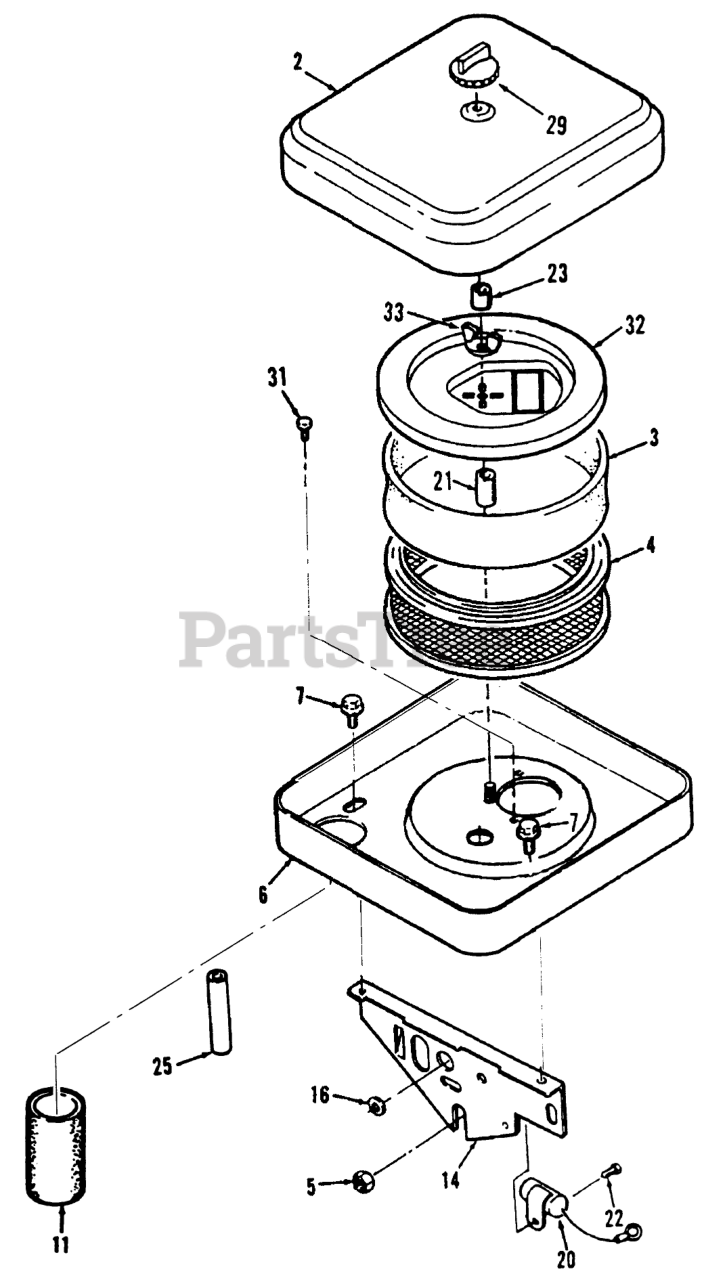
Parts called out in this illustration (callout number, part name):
2	AIR-CLEANER COVER
3	AIR CLEANER ELEMENT
4	Stationary Guard
6	AIR-CLEANER HOUSING
7	SCREW-TAPPING
11	AIR INTAKE TUBE
14	SUPPORT-AIR CLEANER
16	Grommet
20	Capacitor (300 VD)
22	SCREW #10-32 X 5/8
23	SPACER-RUBBER
25	BREATHER TUBE
29	KNOB-TOOL LESS
31	MACHINE SCREW
32	Cover-Element
33	1/4-20 WING NUT
